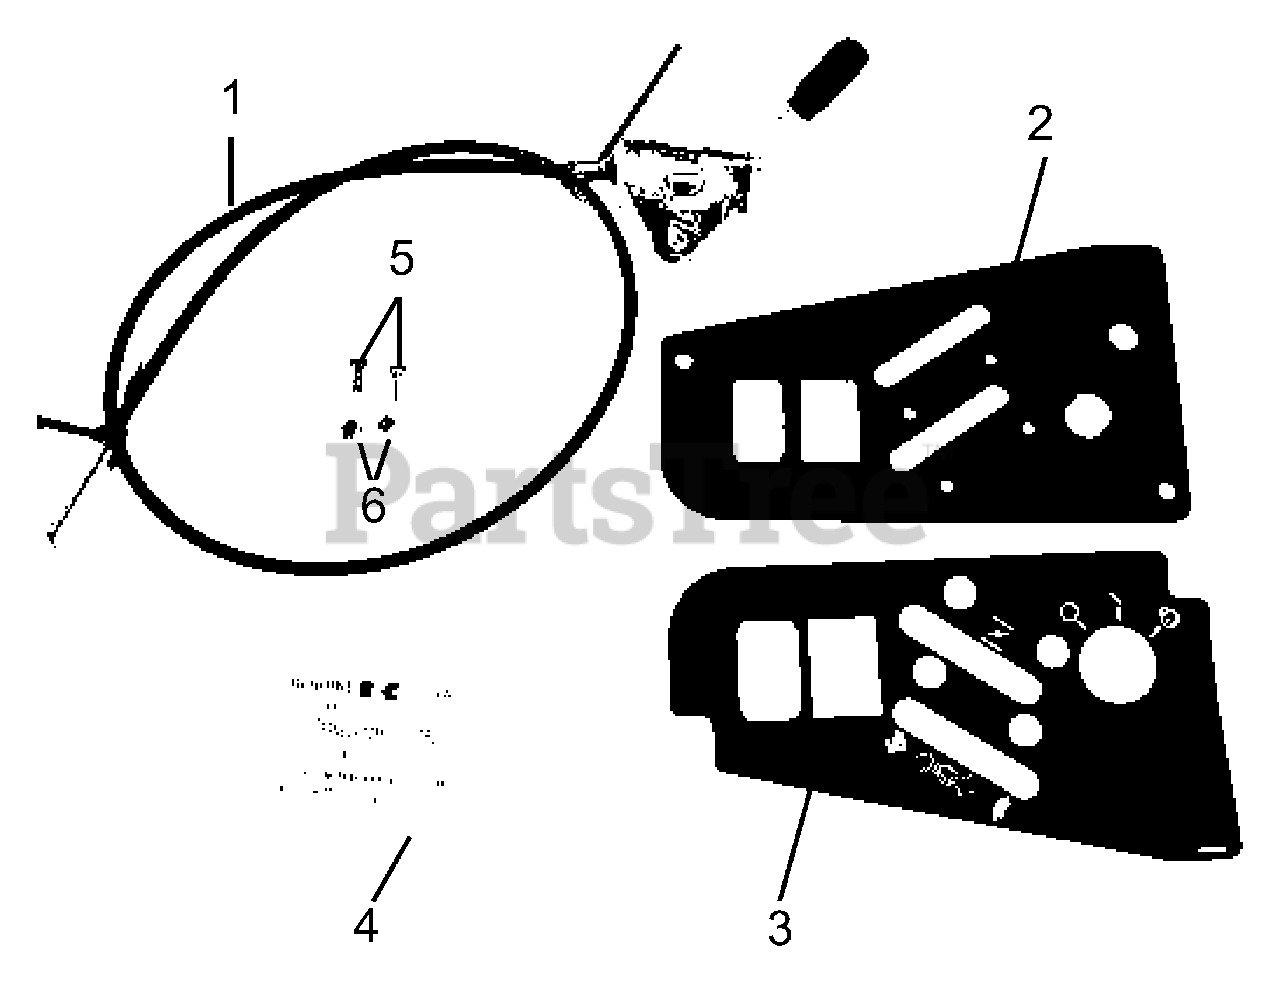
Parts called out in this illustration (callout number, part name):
1	Choke Cable
2	Control Panel
3	Control Panel Decal
4	Kawasaki Control Panel
5	10-24 x 1/2" Machine Screw
6	10-24 Nylon Locknut
